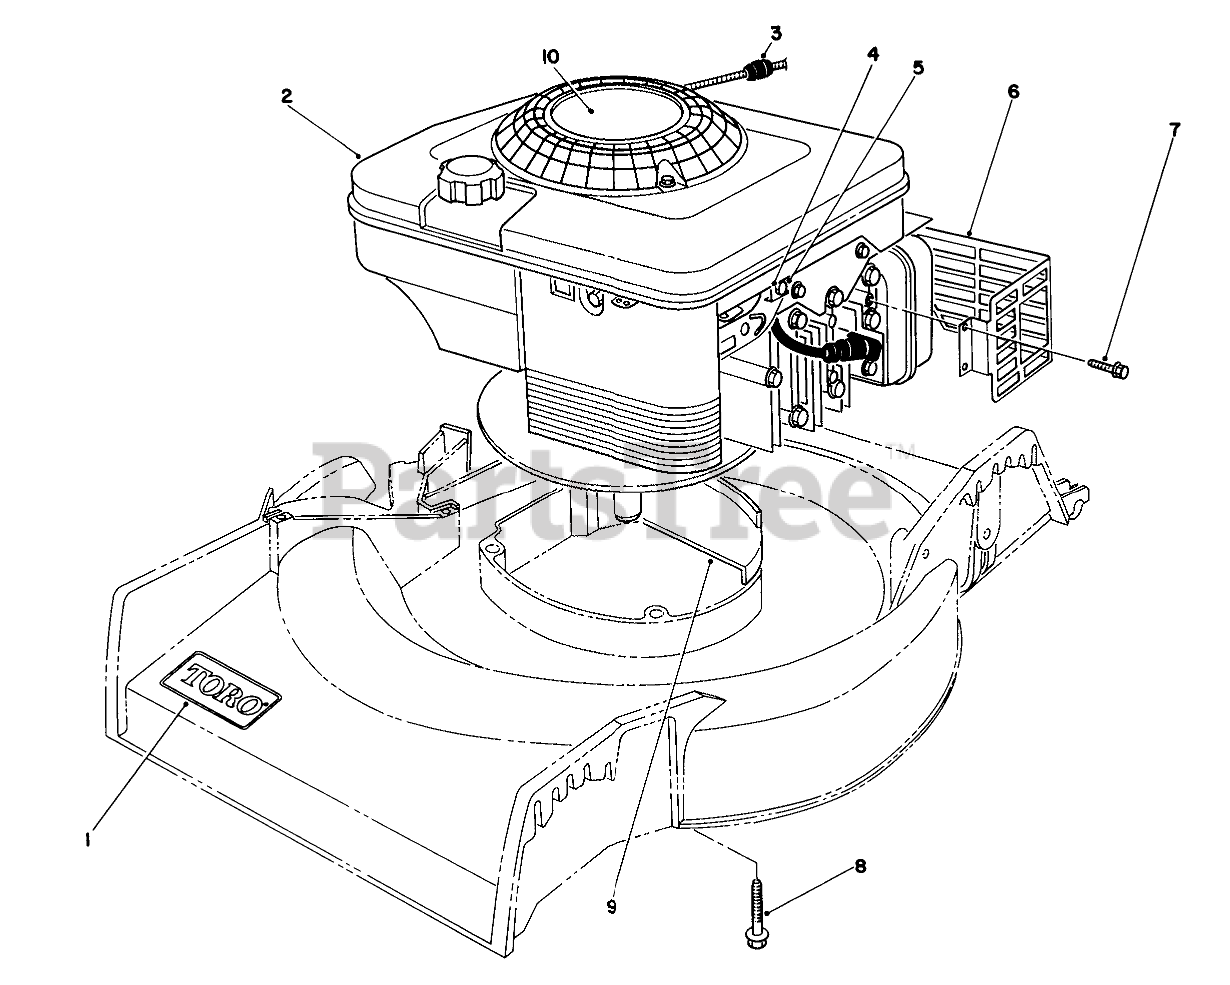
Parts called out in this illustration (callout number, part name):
1	DECAL
3	STOP-ROPE
4	CLAMP-CASING
5	CLAMP SCREW F/W ENGINE
6	SHIELD-MUFFLER
7	SCREW-HWH
8	THD FORM SCREW
9	HOUSING CAP
10	DECAL-ENGINE F/W ENGINE
